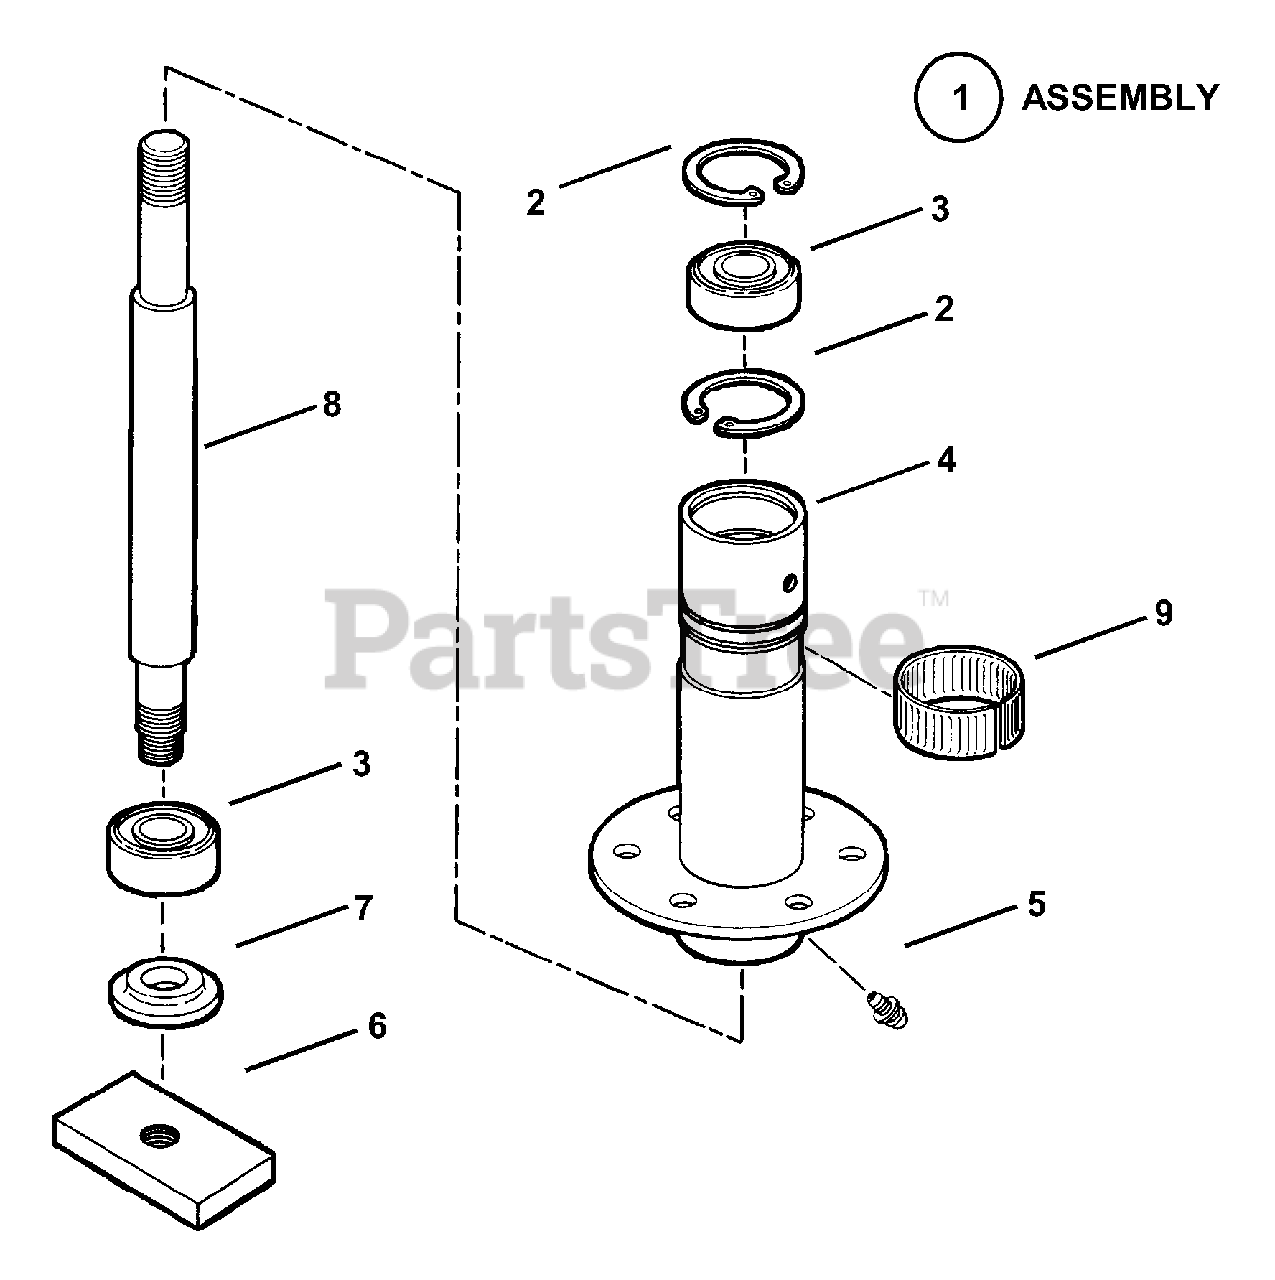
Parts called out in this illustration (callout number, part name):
1	ASSEMBLY, Spindle Housing
2	RING, 1.75" Internal Retaining
3	BEARING, Spindle
4	HOUSING, Spindle (7.5" high)
5	FITTING, Lube (Press fit for .187 hole-no ball)
6	HOLDER, Blade
7	WASHER, Spindle
8	SPINDLE (9.5" Long)
9	RING, Tolerance (.75" high)
